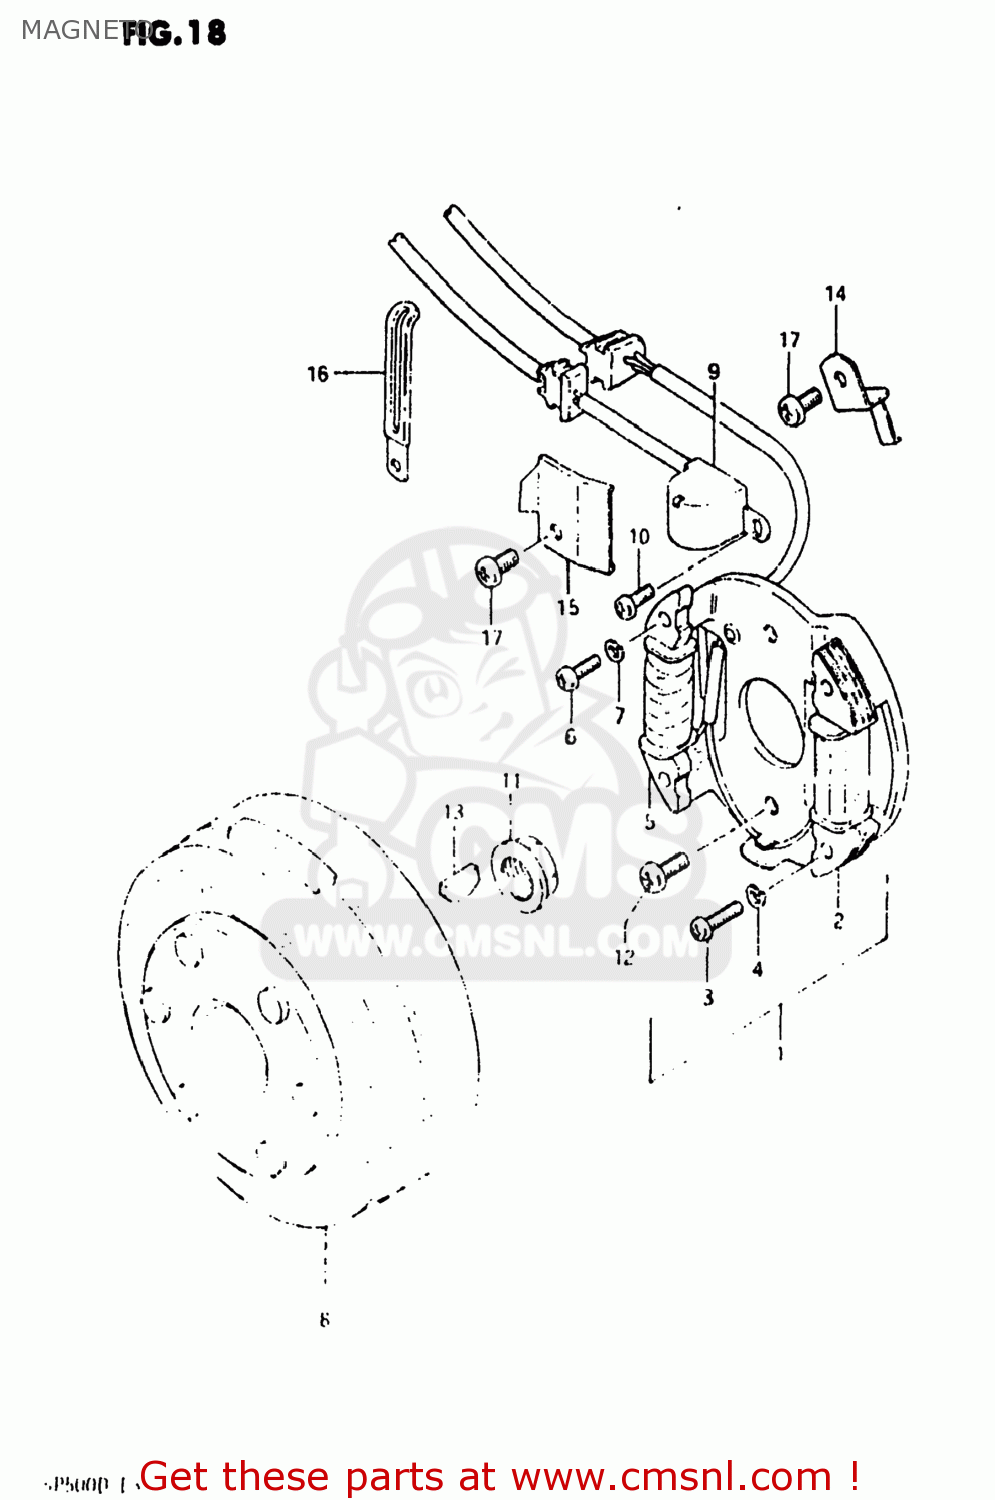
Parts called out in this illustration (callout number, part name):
1	STATOR ASSEMBLY
2	COIL,LIGHTING
3	SCREW
4	LOCK WASHER
5	COIL,PRIMARY
6	SCREW
7	LOCK WASHER
8	ROTOR,FLYWHEEL
9	COIL ASSY,PICK UP
10	SCREW (SUS)
11	NUT,GENERATOR ROTOR
12	SCREW
13	KEY 4MM
14	CLAMP,MAGNETO LEAD WIRE
15	CLAMP,MAGNETO LEAD WIRE
16	CLAMP
17	SCREW
